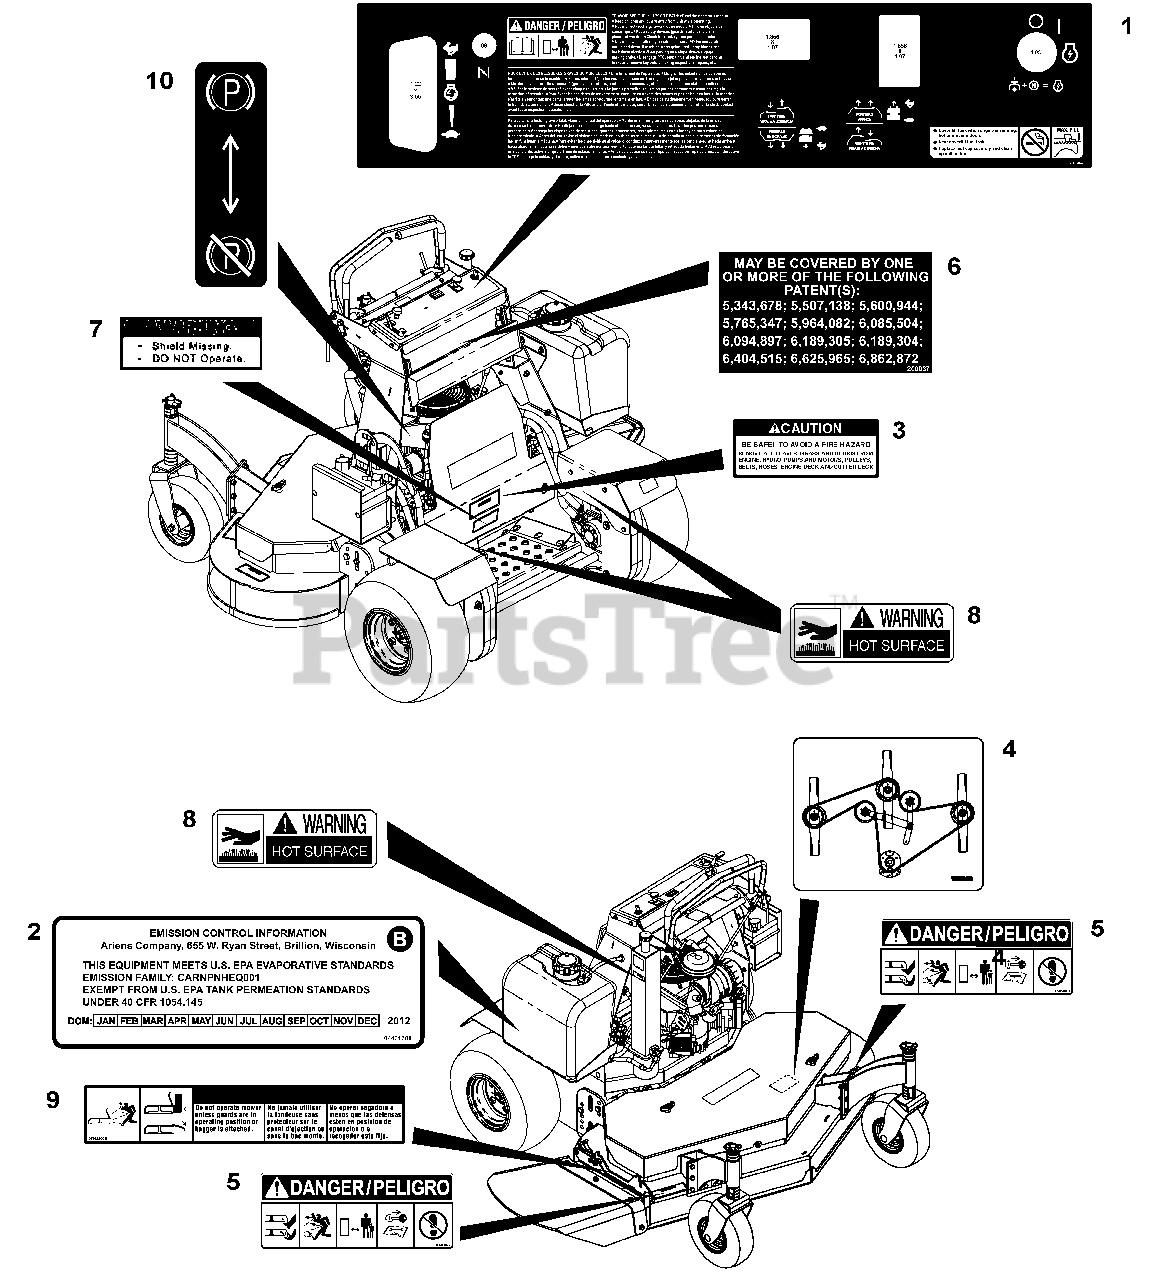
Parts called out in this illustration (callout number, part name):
1	Decal, Console Gravely Prostance
2	Label, EPA Non Comp Fuel Tank
3	Decal, Debris
4	Decal, Belt Path
5	Decal, Mower Pan Danger
6	Decal, Patent
7	Decal, Warning Sheild Missing
8	Label, Warning Hot Surface
9	Decal, Warning
10	Decal, Park Brake
